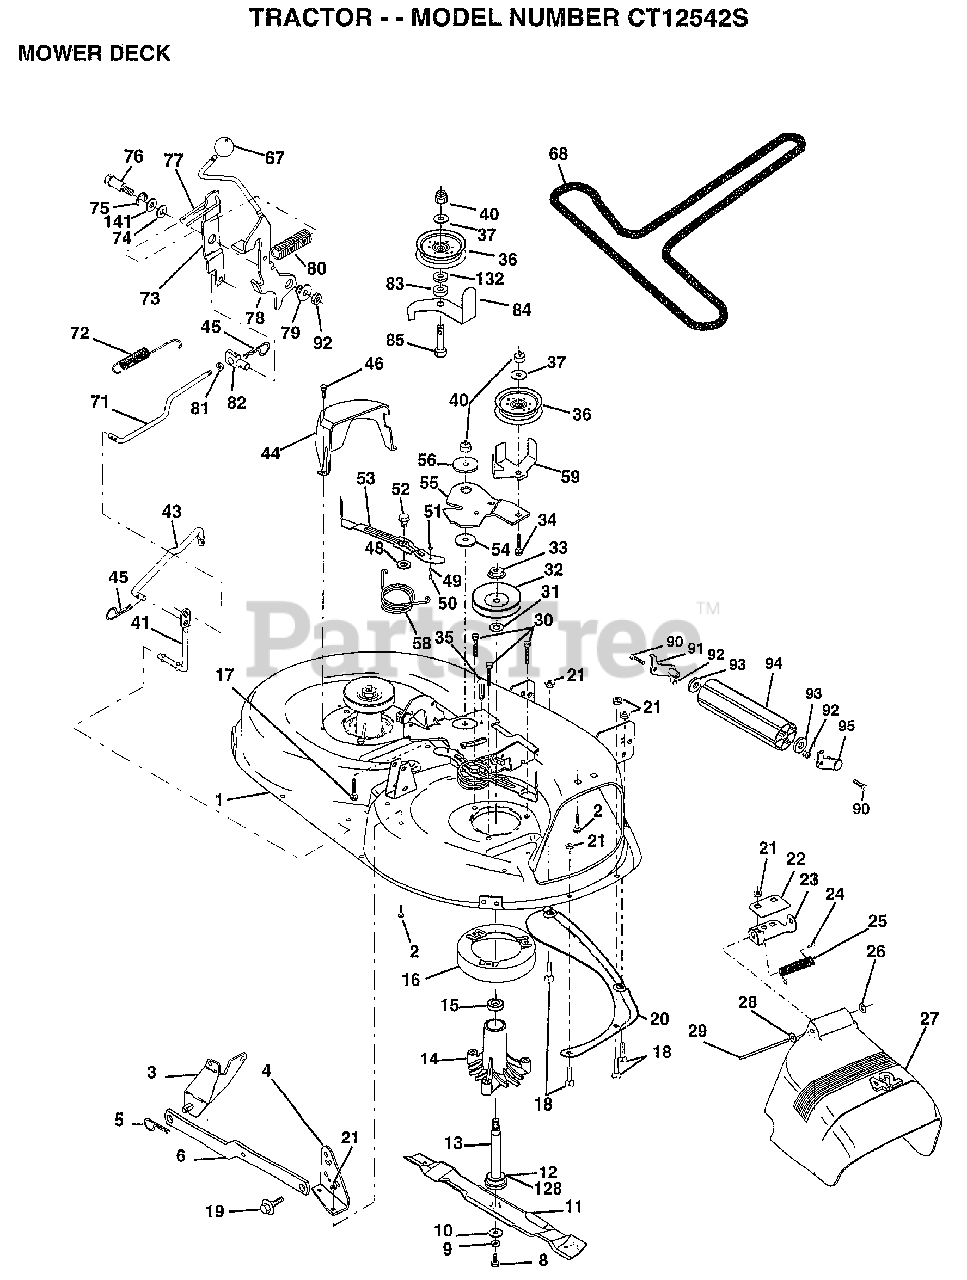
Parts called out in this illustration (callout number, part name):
1	"HOUSING ASSY.42"""
2	BOLT
3	BRKT ASM SWAY BAR
4	BRKT DECK SW BAR
8	BLADE BOLT
10	WASHER.HARD.BLADE
11	"BLADE.42"" HIPERF"
12	BEARING.BALL
14	HSG ASM MANDREL
15	BEARING
16	STRIPPER RND MWR
17	BOLT RDHD 3/8-16
18	BOLT
19	BOLT SHD 5/16-18
20	BAFFLE VORTEX 42
22	STIFFENER BRKT
23	DEFLECTOR BRKT
24	CAP-SLEEVE LT
25	SPRING TORSION
26	NUT PUSH M
27	DEFLECTOR.SHIELD
28	WASHER
29	HINGE ROD
30	"SCREW-THD ROLL,WA"
31	WASHER
32	PULLEY.MANDREL.42
34	BOLT
35	XMAS TREE FASTNER
36	FLAT IDLER PULLEY
37	WASHER
41	PIVOT ROD
43	ROD CLUTCH W/NIBS
44	GUARD MAND LH BLK
45	RETAINER M
46	SCREW.1/4-20X5/8
48	HARD SMALL WASHER
49	ROLLER ASM-CAM
50	SHOULDER BOLT
51	LOCKNUT
52	BOLT.SHLD.5/16-18
53	BRAKE PAD ARM ASM
54	HARDENED WASHER
55	ARM-IDLER
56	SPACER RETAINER
58	SPRING TORSN BRAK
59	GUARD IDLER TUV
67	KNOB.RD.7/16-14
68	BELT.V.T-PATH
71	ROD CLUTCH 38/42
72	RETURN SPRING
73	CLUTCH ARM SECOND
74	WASHER
75	RING
76	SHOULDER BOLT
77	SPRING KEEPER
78	LEVER.ASM.CLUTCH
79	BUSHING
80	SPRING.CLUTCH.MWR
81	NUT
82	TRUNION ADJ
83	WASHER
84	"KEEPER-BELT,FIXED"
85	BOLT
90	BOLT
92	NUT
93	WASHER
128	WASHER.FELT.
132	WASHER GT
141	WASHER .T
